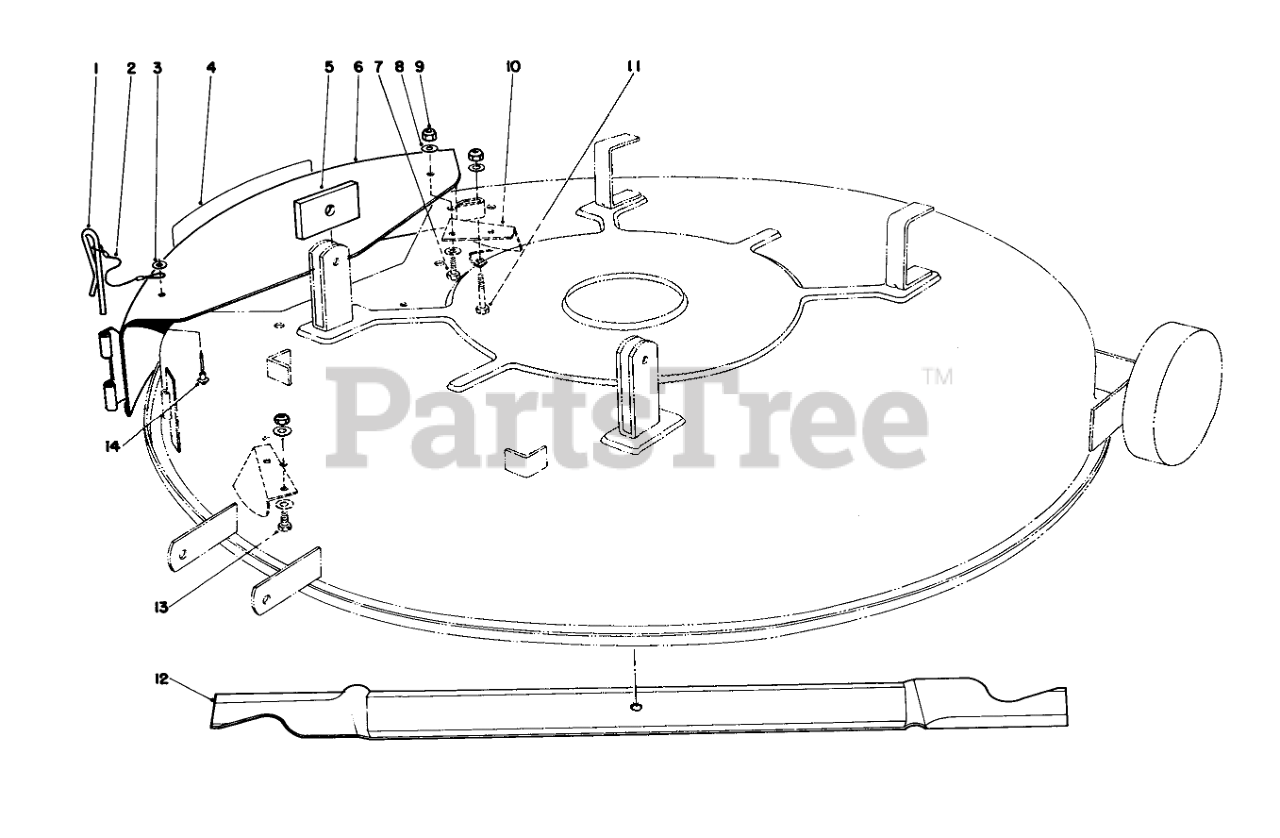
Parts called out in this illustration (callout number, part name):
1	PIN-LOCKING, CHUTE
2	LANYARD
3	WASHER-PLAIN
4	COVER DECAL
5	SPACER
6	Cover-Mulcher Assembly (Incl. Ref. #1-4 & 14)
7	SCREW-HH
8	WASHER-PLAIN
9	NUT-LOCK, NI
10	KICKER B
11	SCREW-HH
12	Blade
13	SCREW-HH
14	RIVET-BLIND
